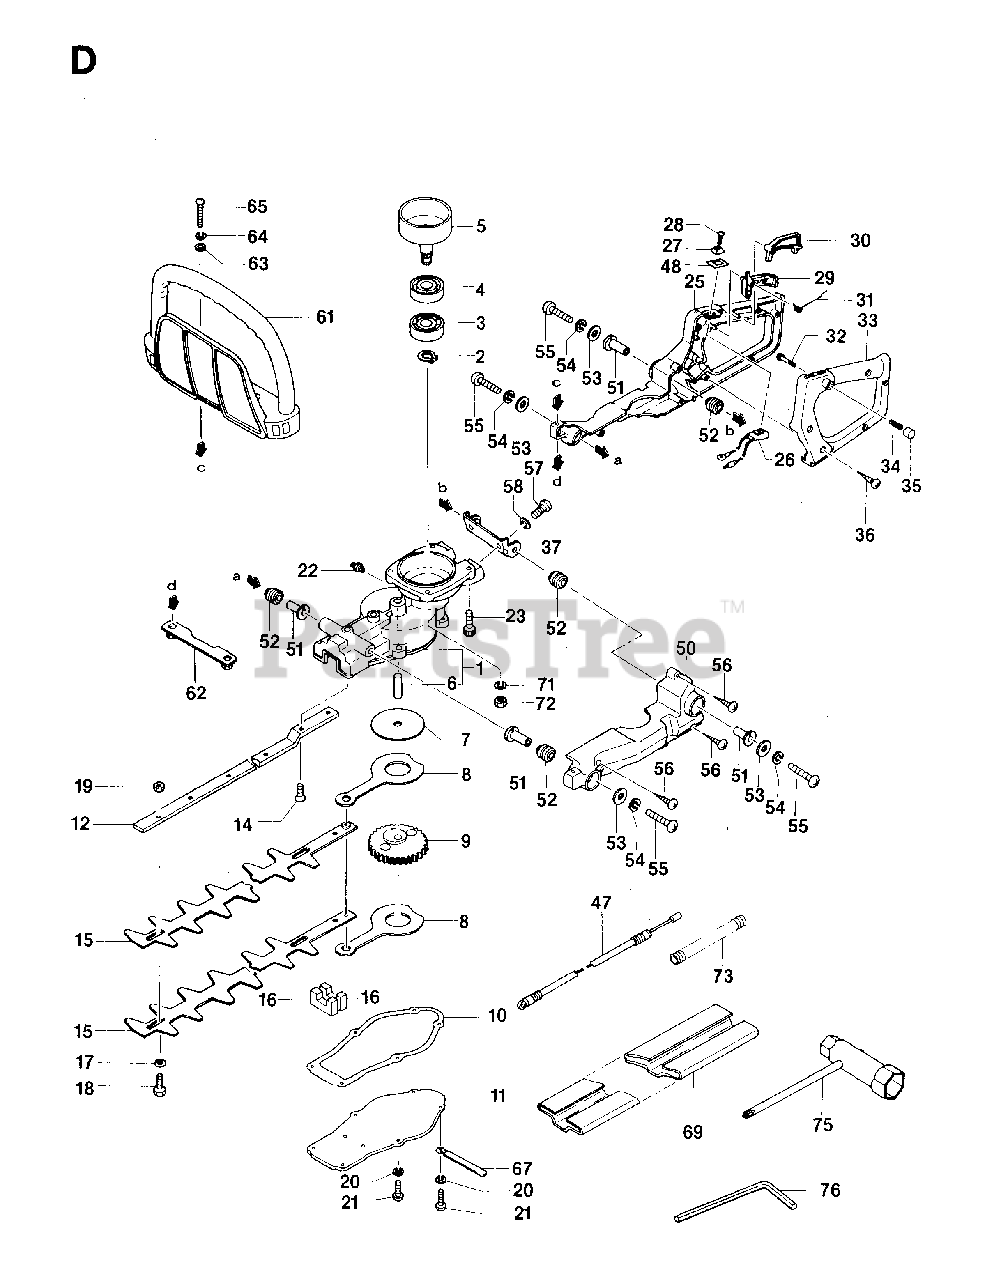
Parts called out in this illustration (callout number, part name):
2	RETAINING RING SGA 15
19	NUT
20	SPRING WASHER 4.1X7.1
54	SPRING WASHER
55	SCREW MC6S 5X30
57	SCREW MC6S 5X12
58	SPRING WASHER
63	WASHER 5.3X12
65	SCREW MC6S 5X40
71	SPRING WASHER
72	NUT M6M M6
